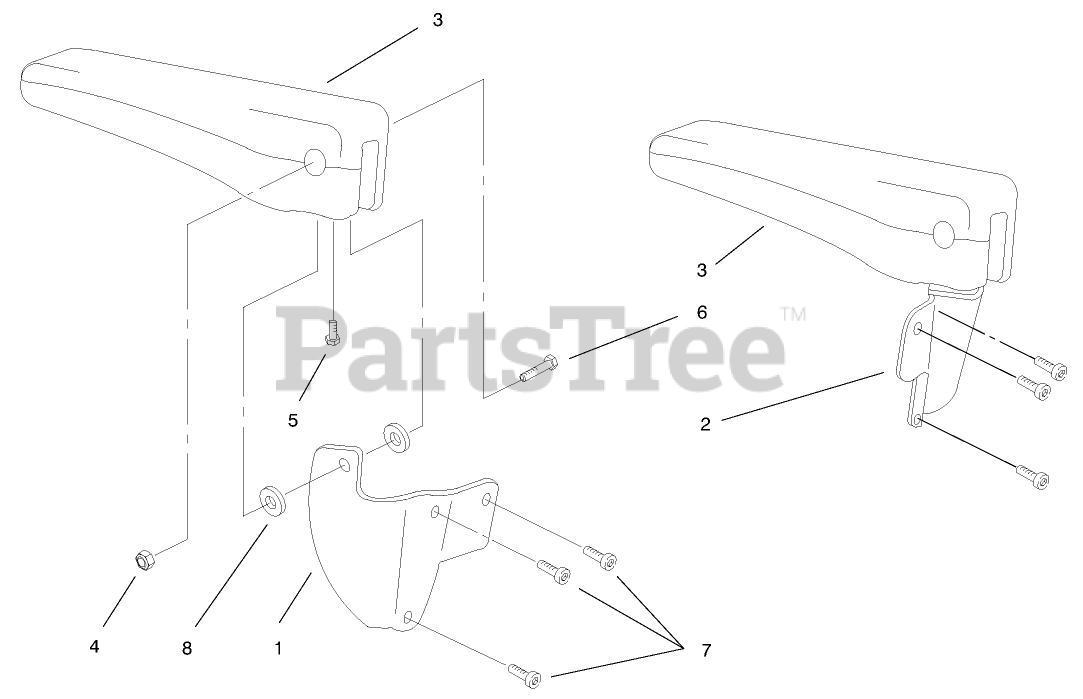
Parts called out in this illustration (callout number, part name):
1	LH ARM BRACKET
2	RH ARM BRACKET
3	ARMREST
4	3/8-16 ACORN LOCKNUT
5	3/8-16 X 3/4 SCREW
6	3/8-16X1-1/2 SCREW
7	3/8-16 X 5/8 SCREW
8	NYLON SPACER
